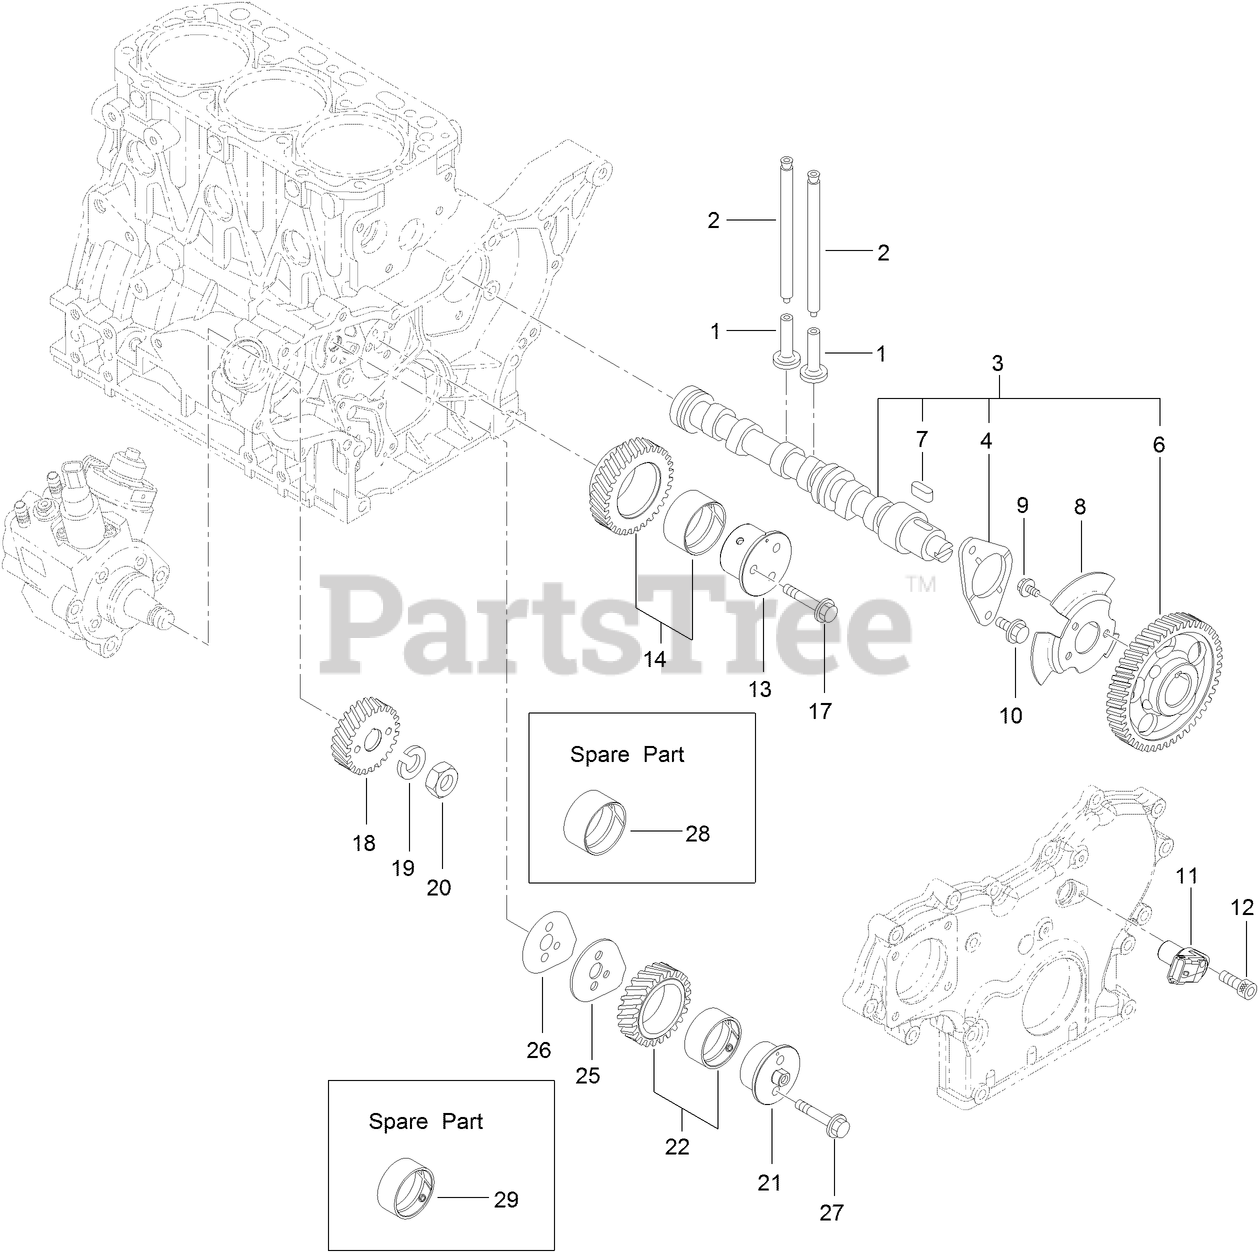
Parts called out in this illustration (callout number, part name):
1	TAPPET
2	ROD-PUSH
3	CAMSHAFT ASM
4	METAL-THRUST
6	GEAR-CAMSHAFT
8	PULSER-CAMSHAFT
11	SENSOR-REV, GEAR
13	SHAFT-IDLE, GEAR A
14	IDLE GEAR A ASM
18	GEAR-PUMP, SUPPLY
19	WASHER-SPRING
20	NUT-LOCK
21	SHAFT-IDLE, GEAR B
22	IDLE GEAR B ASM
25	PLATE-IDLE, SHAFT
26	GASKET-IDLE, SHAFT B
28	BUSHING
29	BUSHING
